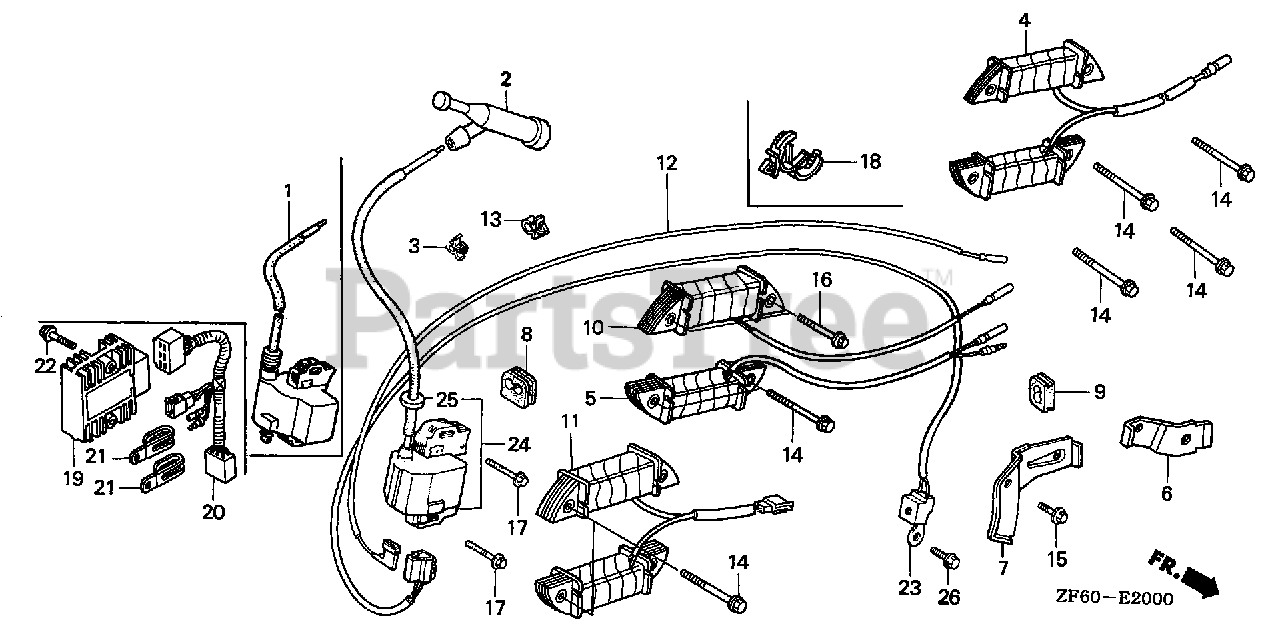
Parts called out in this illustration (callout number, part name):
1	COIL ASSY., IGNITION
2	CAP ASSY., NOISE SUPPRESSOR (NICHIWA Y-EZ RTFM256)
8	GROMMET, WIRE
12	WIRE, STOP SWITCH (430MM)
17	BOLT, FLANGE (6X28) (CT200)
